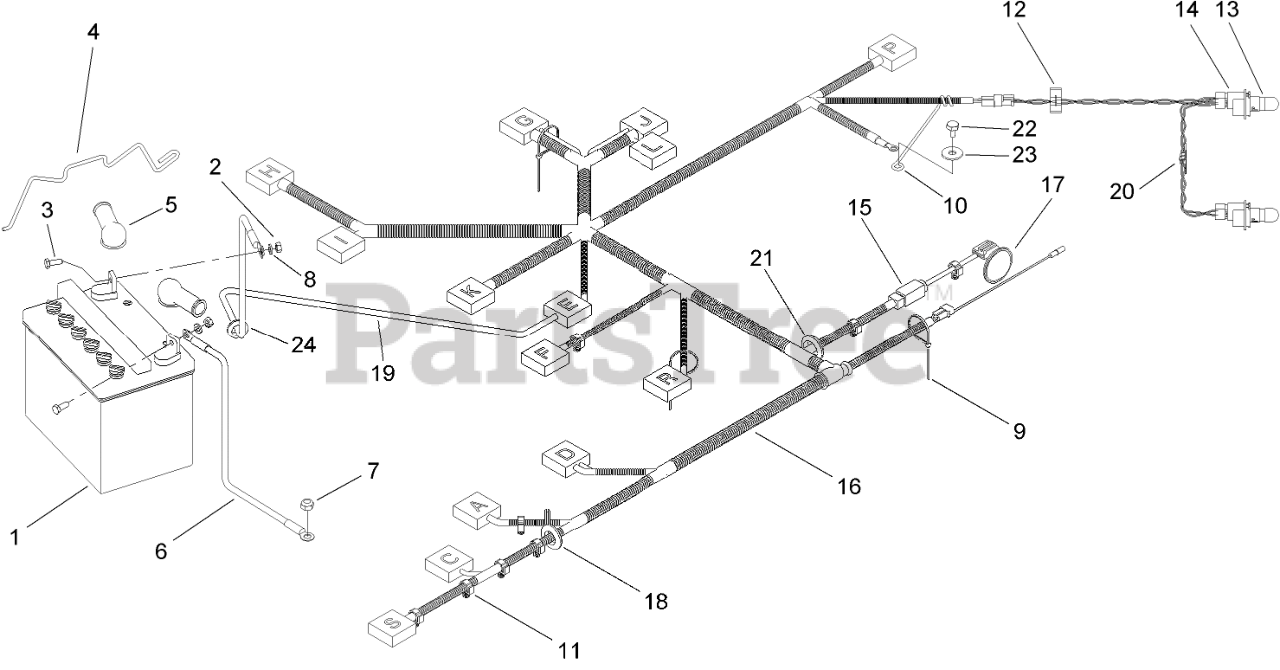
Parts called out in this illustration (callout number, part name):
1	BATTERY-12V
2	NUT-HEX
3	SCREW-HH
4	CLAMP-BATTERY
5	BOOT-RUBBER
6	CABLE-BATTERY, Negative
7	NUT-LOCK, NI
8	WASHER-FLAT
9	TIE-CABLE
10	HOLDER-HARNESS, WIRING
11	CLIP-SNAP
12	HARNESS-WIRE, LIGHTS
13	BULB-LIGHT
14	SOCKET-LIGHT
15	HARNESS-CLUTCH
16	HARNESS-WIRING
18	BUSHING
19	CABLE-BATTERY POSITIVE
20	CLIP-NYLON
21	BUSHING
22	SCREW-HH
23	WASHER-PLAIN
24	GROMMET
